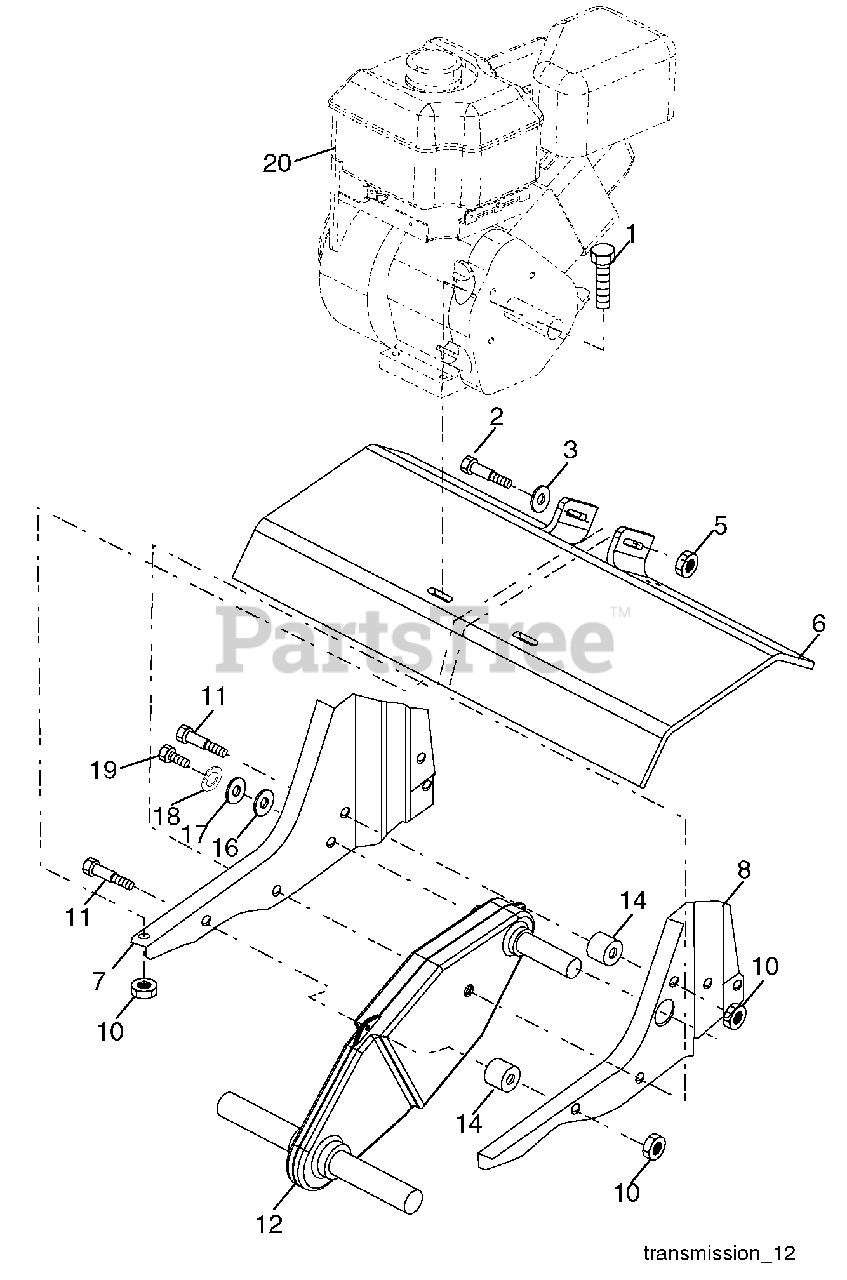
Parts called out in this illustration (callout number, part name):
1	Bolt, Hex 5/16-18 x 1-1/2 Gr. 2
2	Bolt, Hex, Fin 3/8-16 x 3-1/4
3	Washer 13/32 x 13/16 x 11
5	Nut Lock Flg 3/8-16 unc
6	Shield, Tine
7	Bracket, Engine, R.H.
8	Bracket, Engine, L.H.
10	Nut Lock Hex Flg
11	Bolt, Shoulder
12	Transmission
14	Spacer, Split
16	Washer 9/32 x 7/8 x 12 Ga.
17	Washer 9/32 x 1-1/4 x 16 Ga.
18	Washer, Lock 1/4
19	Bolt, Hex 1/4-28 x 3/4 Gr. 5
